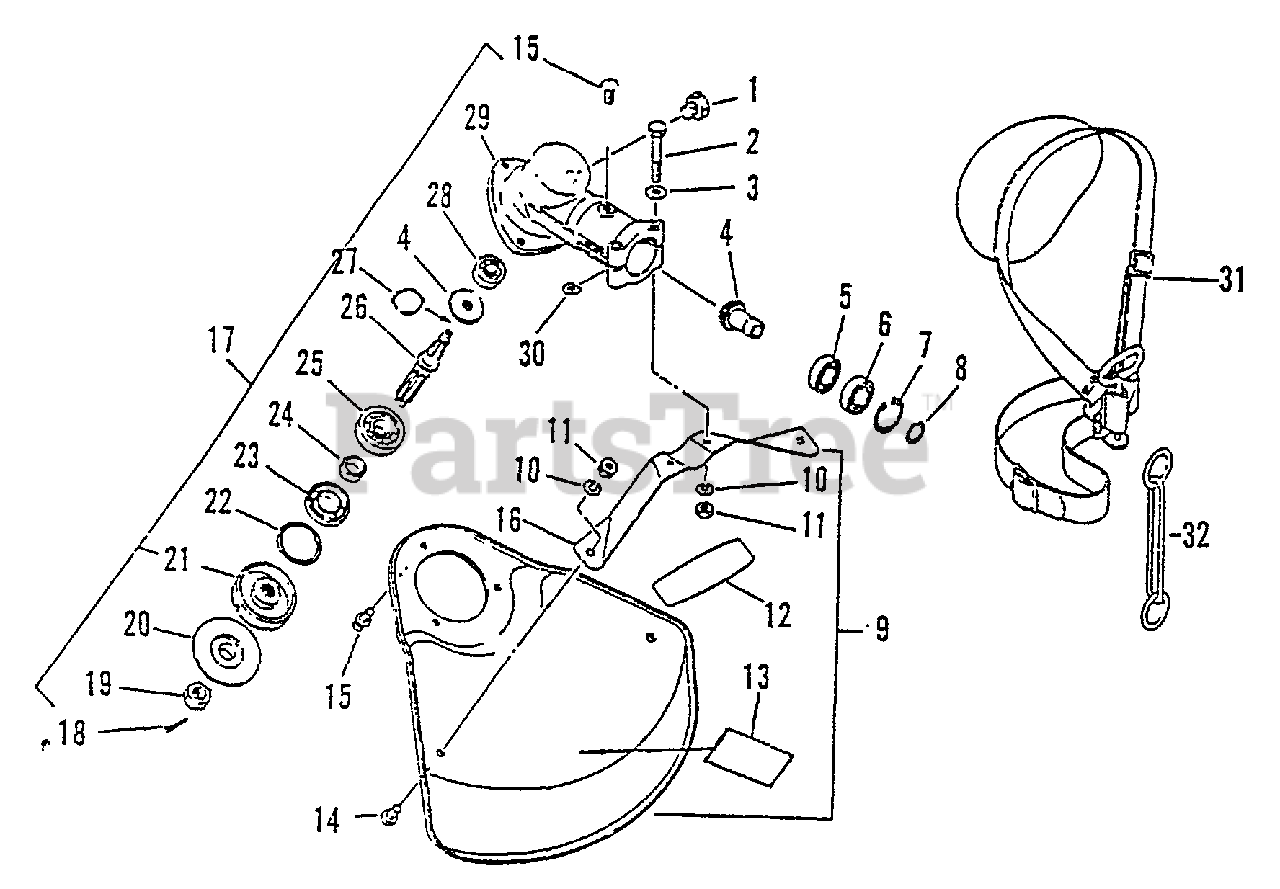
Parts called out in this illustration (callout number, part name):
1	BOLT 8×8 SP
2	BOLT 5×35 SP
3	WASHER, FLAT 5.5×10×0.8
4	GEAR SET
5	BEARING, BALL 6900
6	BEARING, BALL 6900Z
7	RING, SNAP Ø22
8	RING, SNAP Ø12
9	SHIELD ASSY
10	WASHER, SPRING 5
11	NUT M5
12	LABEL, ECHO
13	LABEL - CAUTION
14	SCREW 5×8
15	SCREW 5×10
16	BRACKET, SHIELD MOUNTING
17	GEAR CASE ASSY
18	PIN, COTTER 2×22
20	PLATE, ADAPTOR - LOWER
21	PLATE, ADAPTER - UPPER
22	RING, SNAP Ø32
23	SEAL, OIL 22
24	SPACER 11.8×15×9
25	BEARING, BALL - 6201 C3
26	SHAFT, GEAR
27	RING, SNAP Ø10
28	BEARING, BALL 609
29	HOUSING, GEAR CASE
31	SHOULDER STRAP ASSY
32	HOOK
